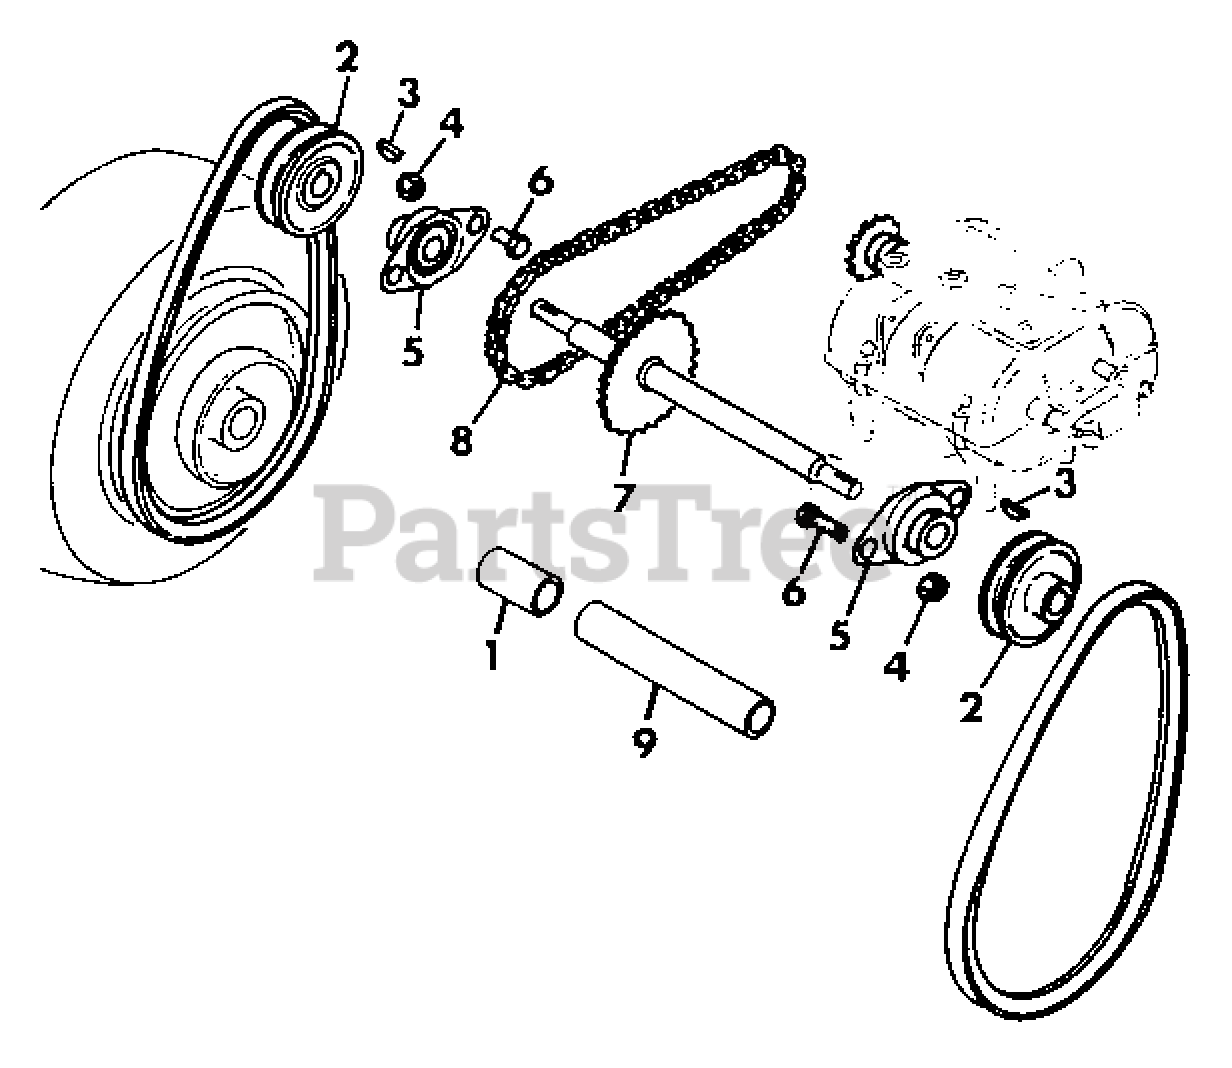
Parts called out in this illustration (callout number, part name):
1	Tube, Plastic
2	Pulley, Jack-Shaft
3	Key, Woodruff 3/16x.750 Hard
4	Nut, Lock 3/8-16
5	Bearing, Fan
6	Bolt, Hex 3/8-16x.75
7	Weldment, Jack-Shaft
8	Chain, American Standard No. 40
9	Tube, Plastic
